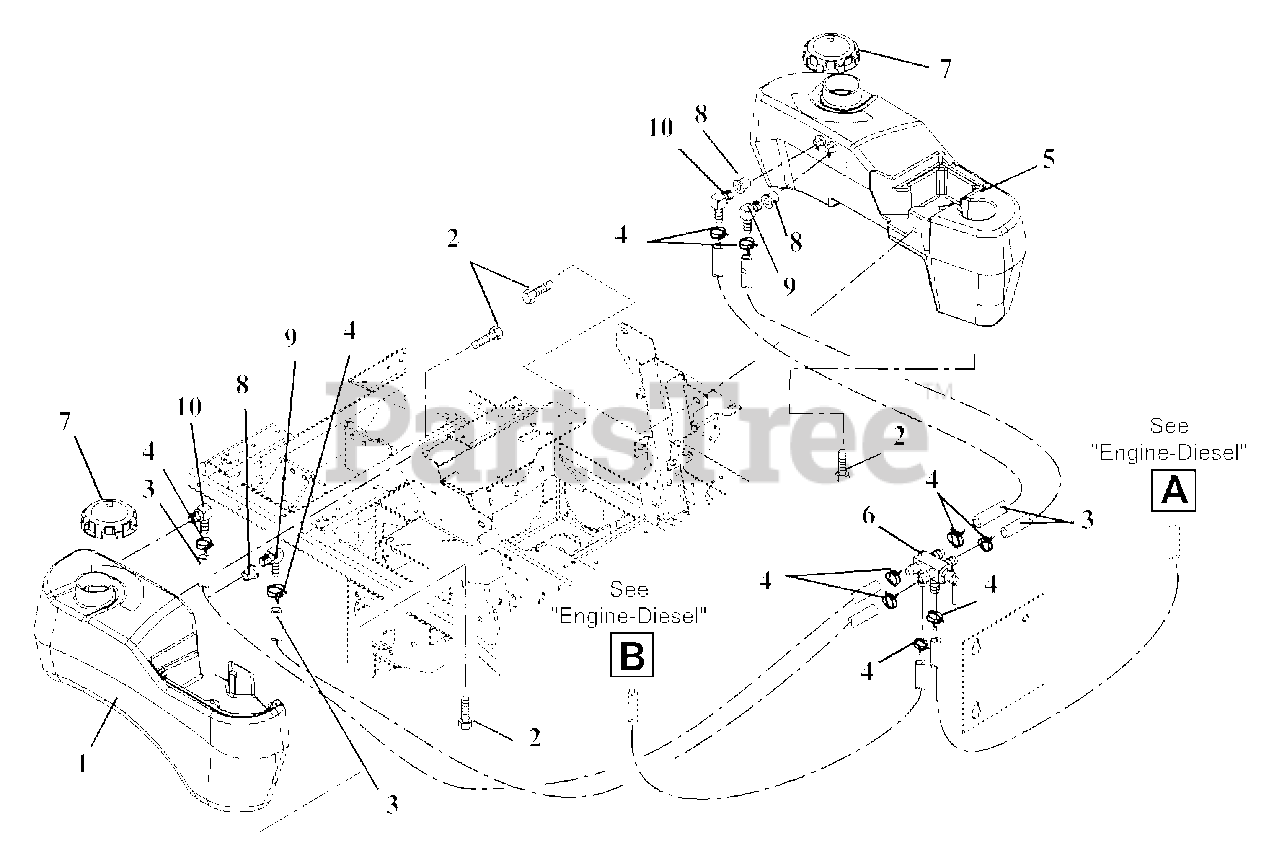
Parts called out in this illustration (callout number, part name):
1	TANK, GAS RH (200 W/RETURN)
2	BOLT, SEMS .31-18 X .62
3	HOSE,5/16 ID
4	CLAMP, HOSE WIRE .520/.550
5	TANK, FUEL-LH(W/RTN)W/O HOSE
6	VALVE, FUEL
7	CAP, FUEL
8	GROMMET, DAPCO VITON #12240
9	FITTING, TANK ELBOW .31 HOSE
10	FITTING, TANK (5/16 ELBOW)
